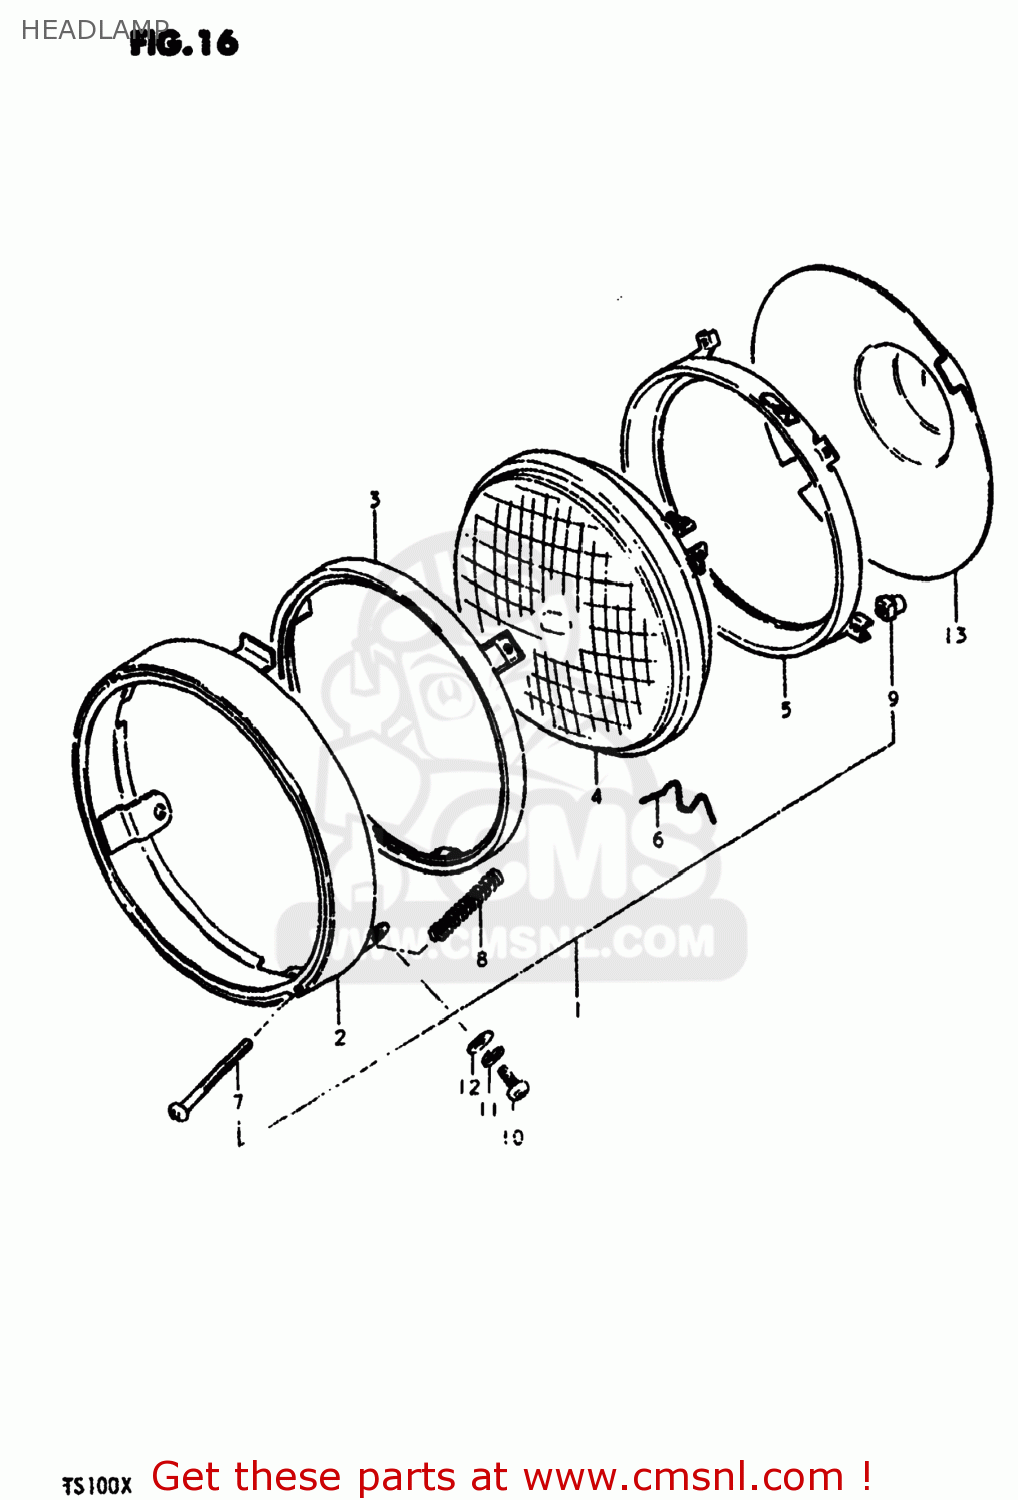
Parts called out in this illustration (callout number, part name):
1	LAMP ASSEMBLY,HEAD
2	RIM
3	RETAINER,HEADLAMP
4	LAMP UNIT
5	RING,HEADLAMP UNIT
6	SPRING,HEADLAMP UNIT
7	SCREW,HEADLAMP ADJUST
8	SPRING,ADJUSTING
9	NUT,HEADLAMP ADJUSTER
10	SCREW
11	LOCK WASHER
12	WASHER
13	COVER,HEADLAMP UNIT
